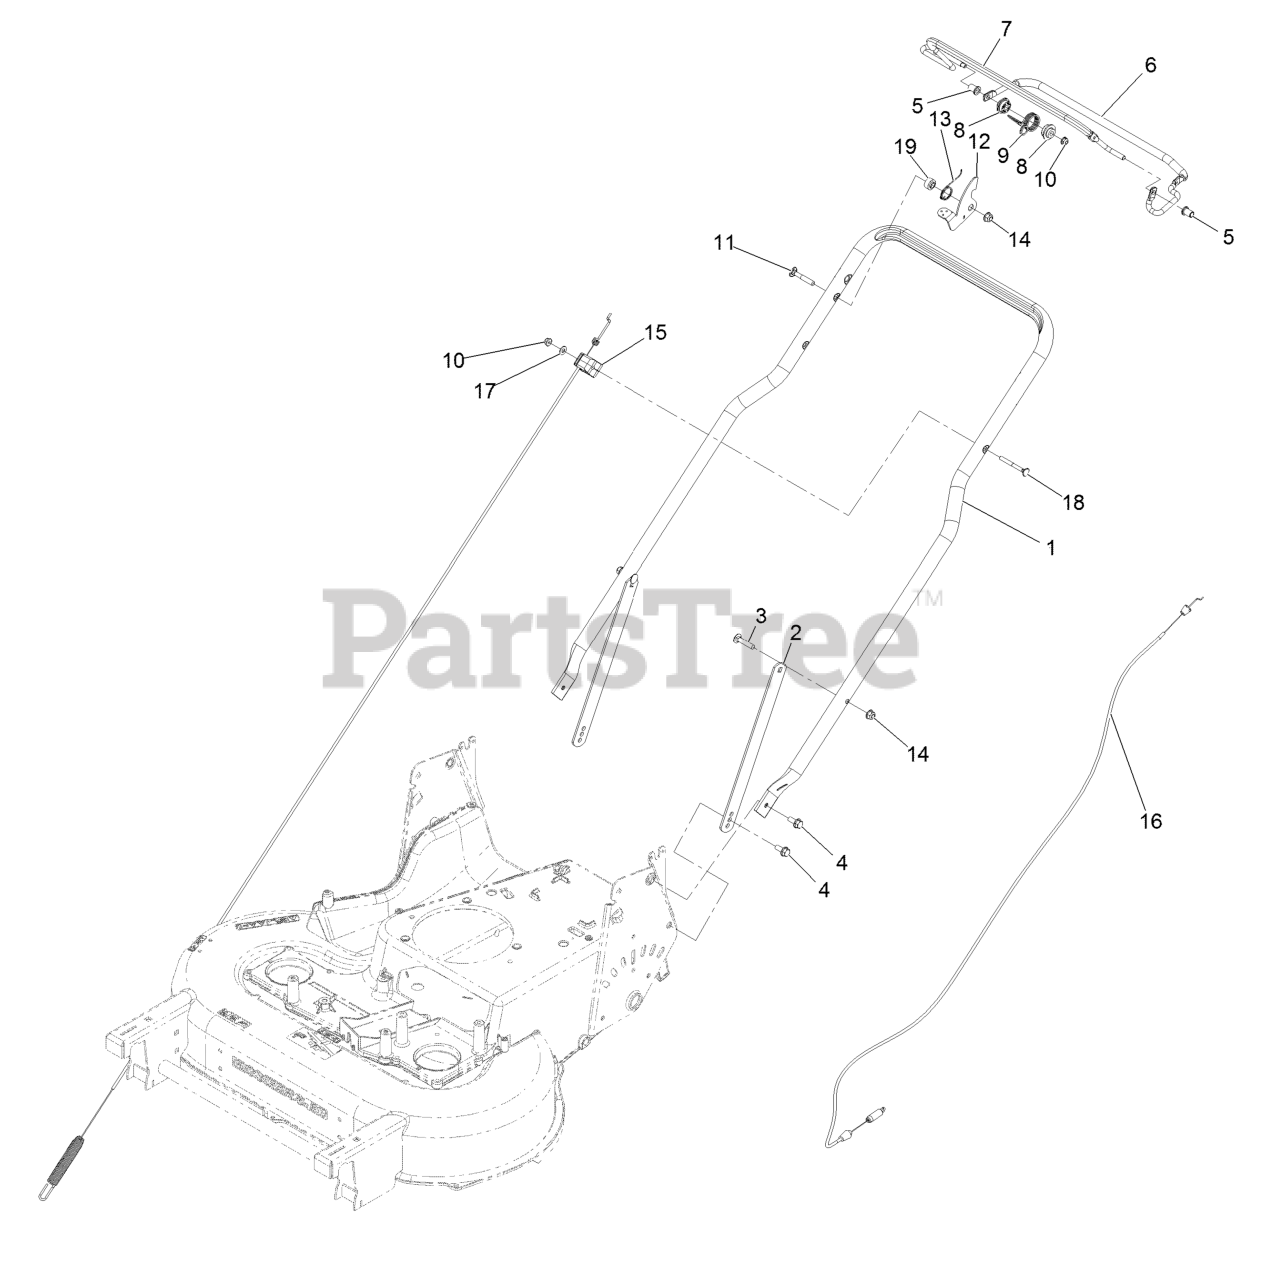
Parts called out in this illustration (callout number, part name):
2	Support-Handle
3	Bolt-Carriage 5/16-18 X 1 1/2
4	Screw-HHF
5	Bushing-Handlebar
6	Bail-Drive Coated
8	Bushing-Spring, Pivot
9	Spring-Return, BBC
10	Nut-Nyloc 1/4-20 Flg
11	Bolt-Carriage 5/16-18 X 2
12	Lever-BBC
13	Spring-Lever, BBC
14	Nut-Nyloc 5/16-18 Flg
15	Cable-Brake, 30" 2-Bail
16	Cable-Traction
17	Washer-Flat
18	Screw-Handle
19	Bushing-Stepped
99	Tie-Cable
